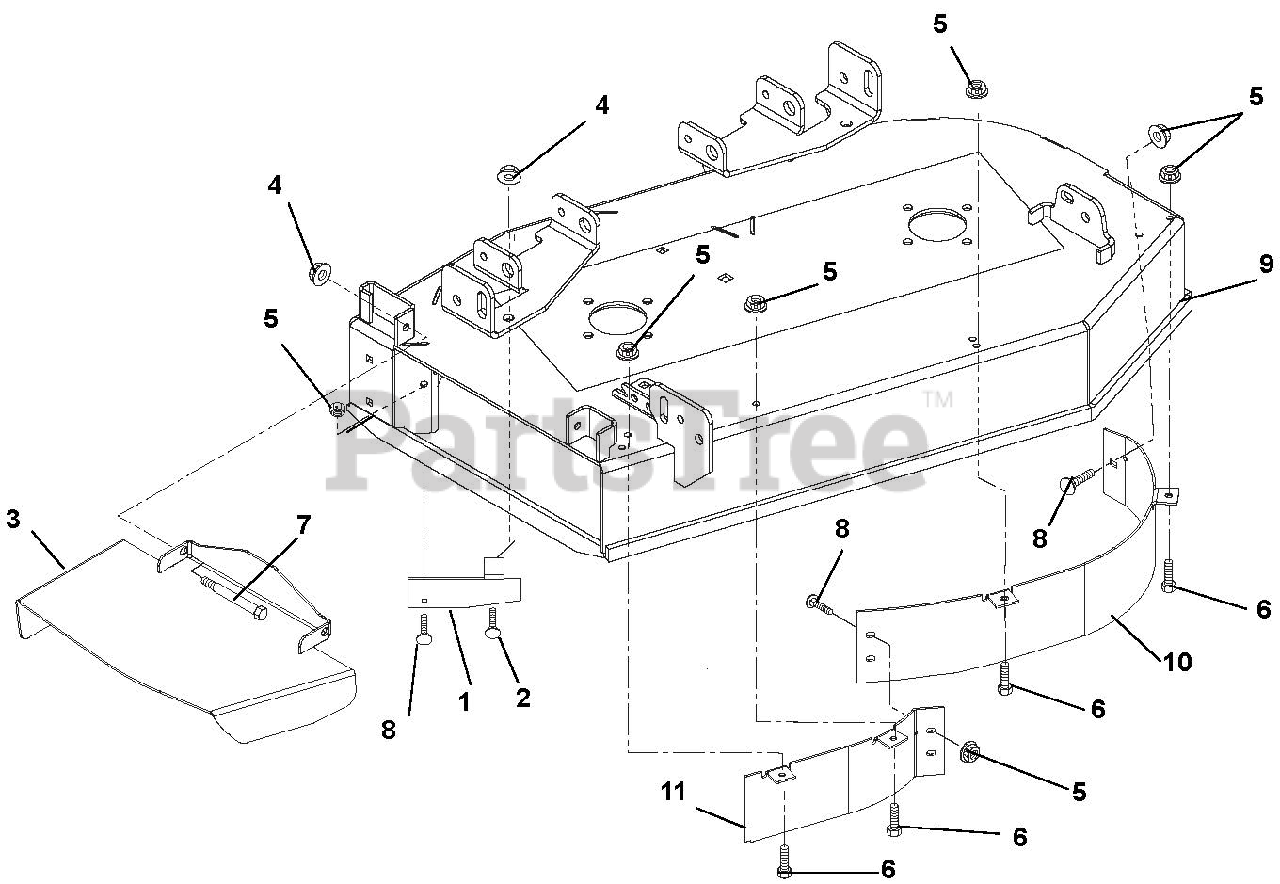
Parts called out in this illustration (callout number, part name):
1	Baffle, Deflector
2	Bolt, Round Head Square Neck .38-16 x 1.25 Grade 5
3	Chute, Discharge
4	Nut, Nyloc Flange 3/8-16
5	Nut, Nyloc Flange 5/8-18
6	Bolt, Hex .31-18 x .75 Grade 5
7	Bolt, Shoulder .38-16 x .50 Socket Head
8	Bolt, Round Head Square Neck .31-18 x .75 Grade 5
9	Weldment, 34" Side Discharge Deck
10	Baffle, 34" Front Left Hand
11	Baffle, 34" Front Right Hand
